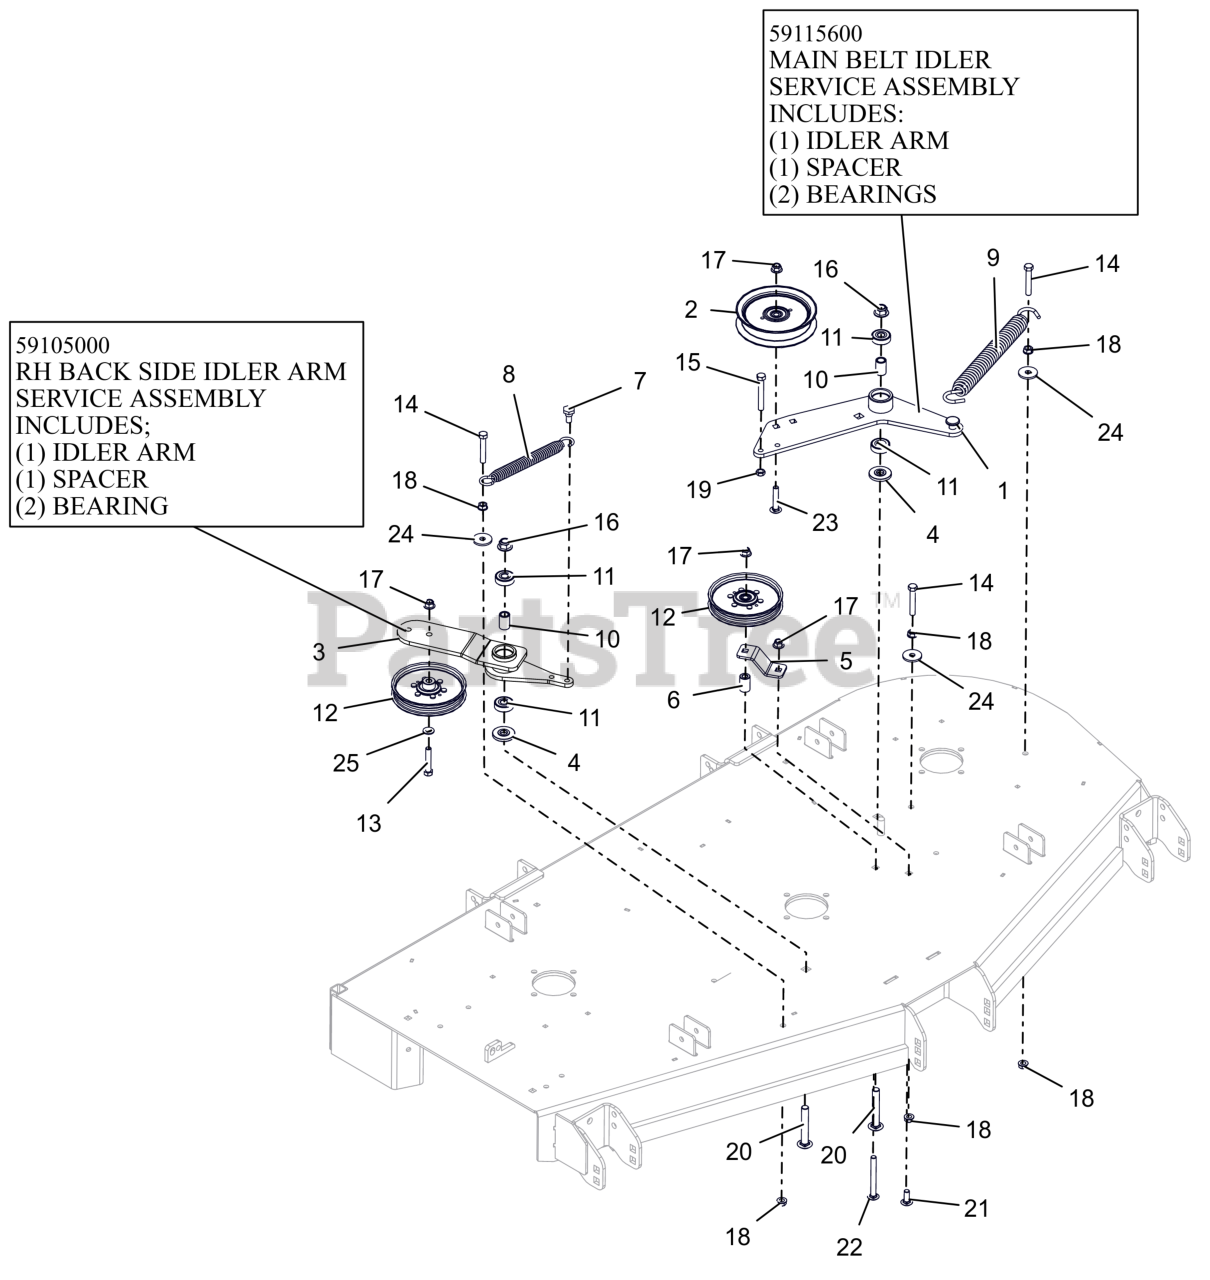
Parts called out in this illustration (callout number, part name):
1	WLDMT, DECK PTO IDLR ARM
1	ASSEMBLY, MAIN BELT IDLER
2	IDLER, FLAT 5.00"
3	WLDMT, DECK RH IDLER ARM
3	RH BACKSIDE IDLER ARM ASSEMBLY
4	SPACER, IDLER ARM
5	PTO FIXED IDLER MTG BRKT -RED
6	BUSHING, SLV .380X.750X1.190
7	BLT,SHLDR EP .38-16X.30 HEX YZ
8	SPRING, EXTENSION
9	SPRING, EXTENSION
10	SPACER .510 X .75 X 1.1485
11	BRG-BALL .500X1.38X.437
12	PULLEY, FLAT IDLER
13	BLT,HEX .38-16X2.00 G5 ZCC
14	BLT,HEX .38-16X2.25 G5 ZCC
15	BLT, HEX .38-16X2.75 G5 ZCC
16	NUT,NYL-FLG .50-13 GF ZCC
17	NUT,NYL-FLG .38-16 GF ZCC
18	NUT, SPNLK-FLG .38-16 G5 ZCC
19	NUT-JAM .375-16 G2 ZCC
20	BTL,RHSSN .500-13 X 3.25 G5 ZCC
21	BLT,RHSSN .38-16X1.00 G5 ZCC
22	BLT,RHSSN .38-16X3.50 G5 ZCC
23	BLT,RHSSN.375-16X2.00 G5 ZCC
24	WSHR,FLT .406X1.375X.135 ZCC
25	WSHR,FLT .406X.812X.065 ZCC
